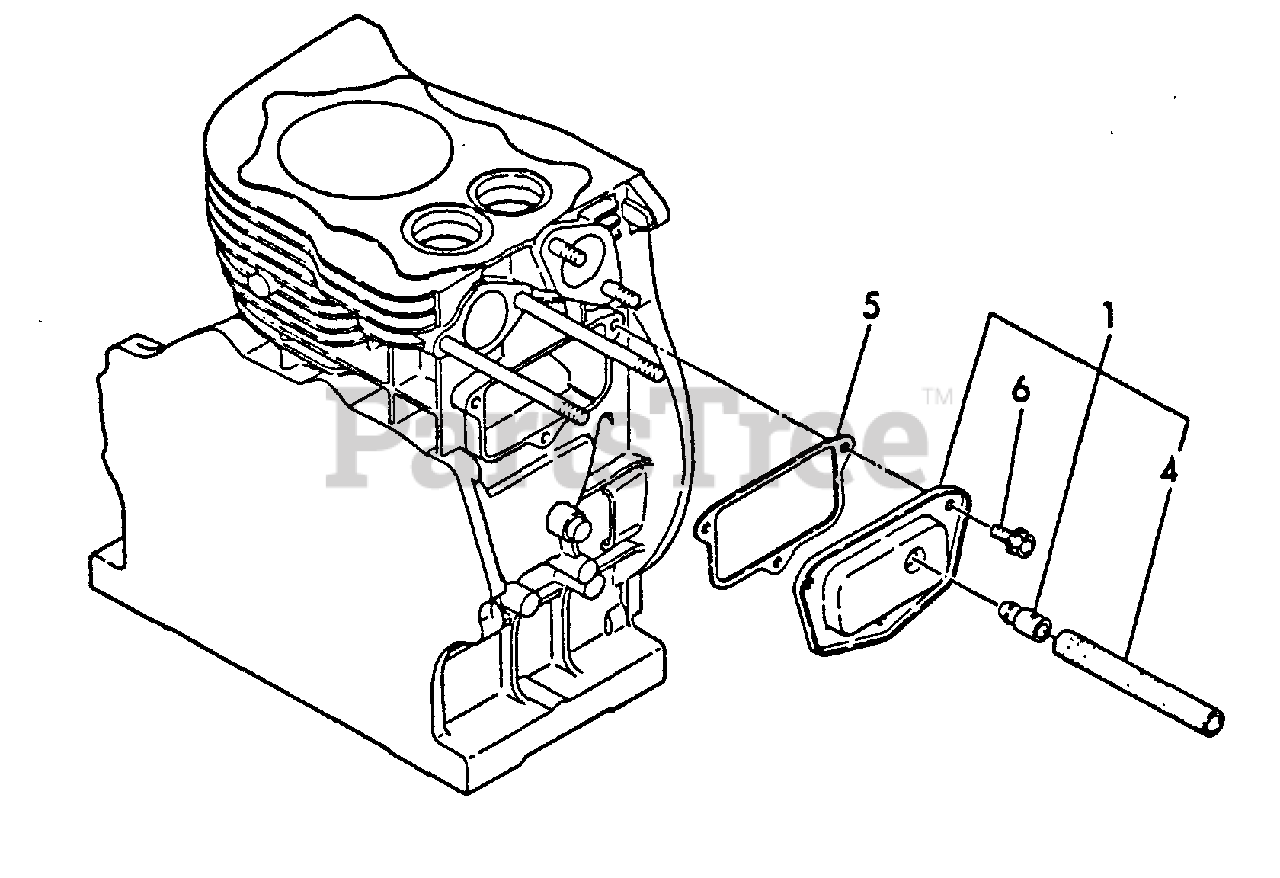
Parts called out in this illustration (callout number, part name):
1	VENT, FUEL TANK
4	PIPE - BREATHER
5	GASKET, BREATHER
6	BOLT - 6X8 -- PLATED
